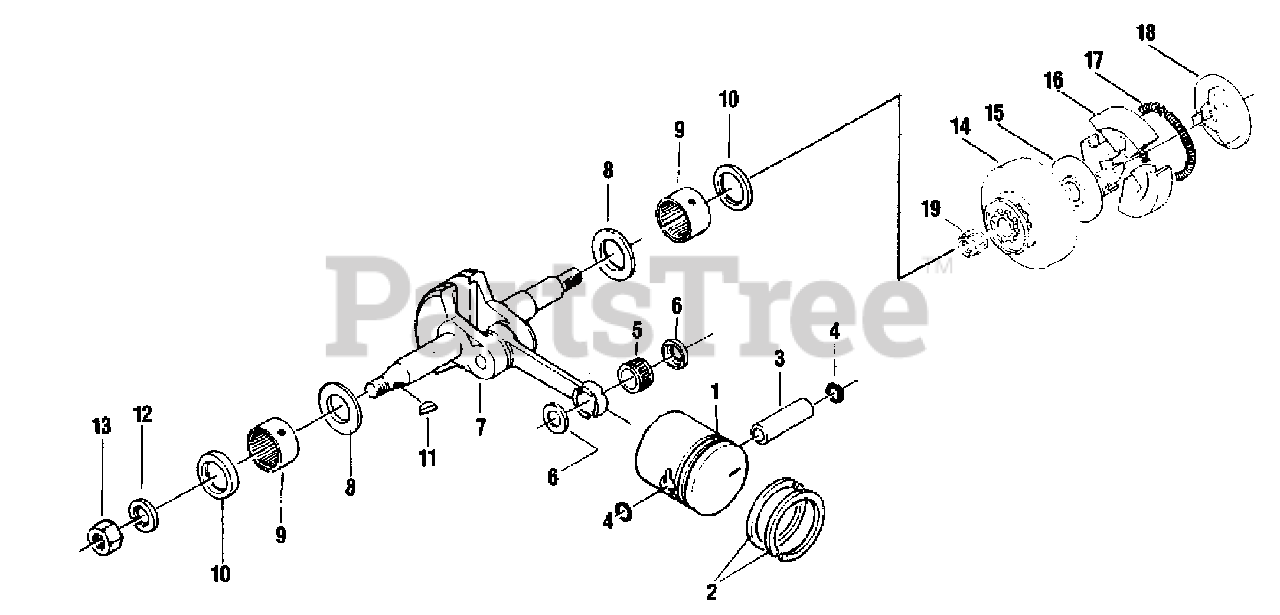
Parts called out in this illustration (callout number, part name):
1	PISTON
2	RING, PISTON
3	PIN, PISTON
4	RING, SNAP
5	BEARING, NEEDLE 10
6	WASHER, THRUST
7	CRANKSHAFT ASSY
8	WASHER, THRUST
9	BEARING, NEEDLE
10	SEAL, OIL
11	KEY, WOODRUFF - 3×10
12	WASHER, SPRING 8
13	NUT
14	CLUTCH DRUM ASSY - 3/8" RIM
15	HUB, CLUTCH
16	SHOE, CLUTCH
17	SPRING, CLUTCH
18	HUB, CLUTCH - OUTER
19	BEARING, NEEDLE
